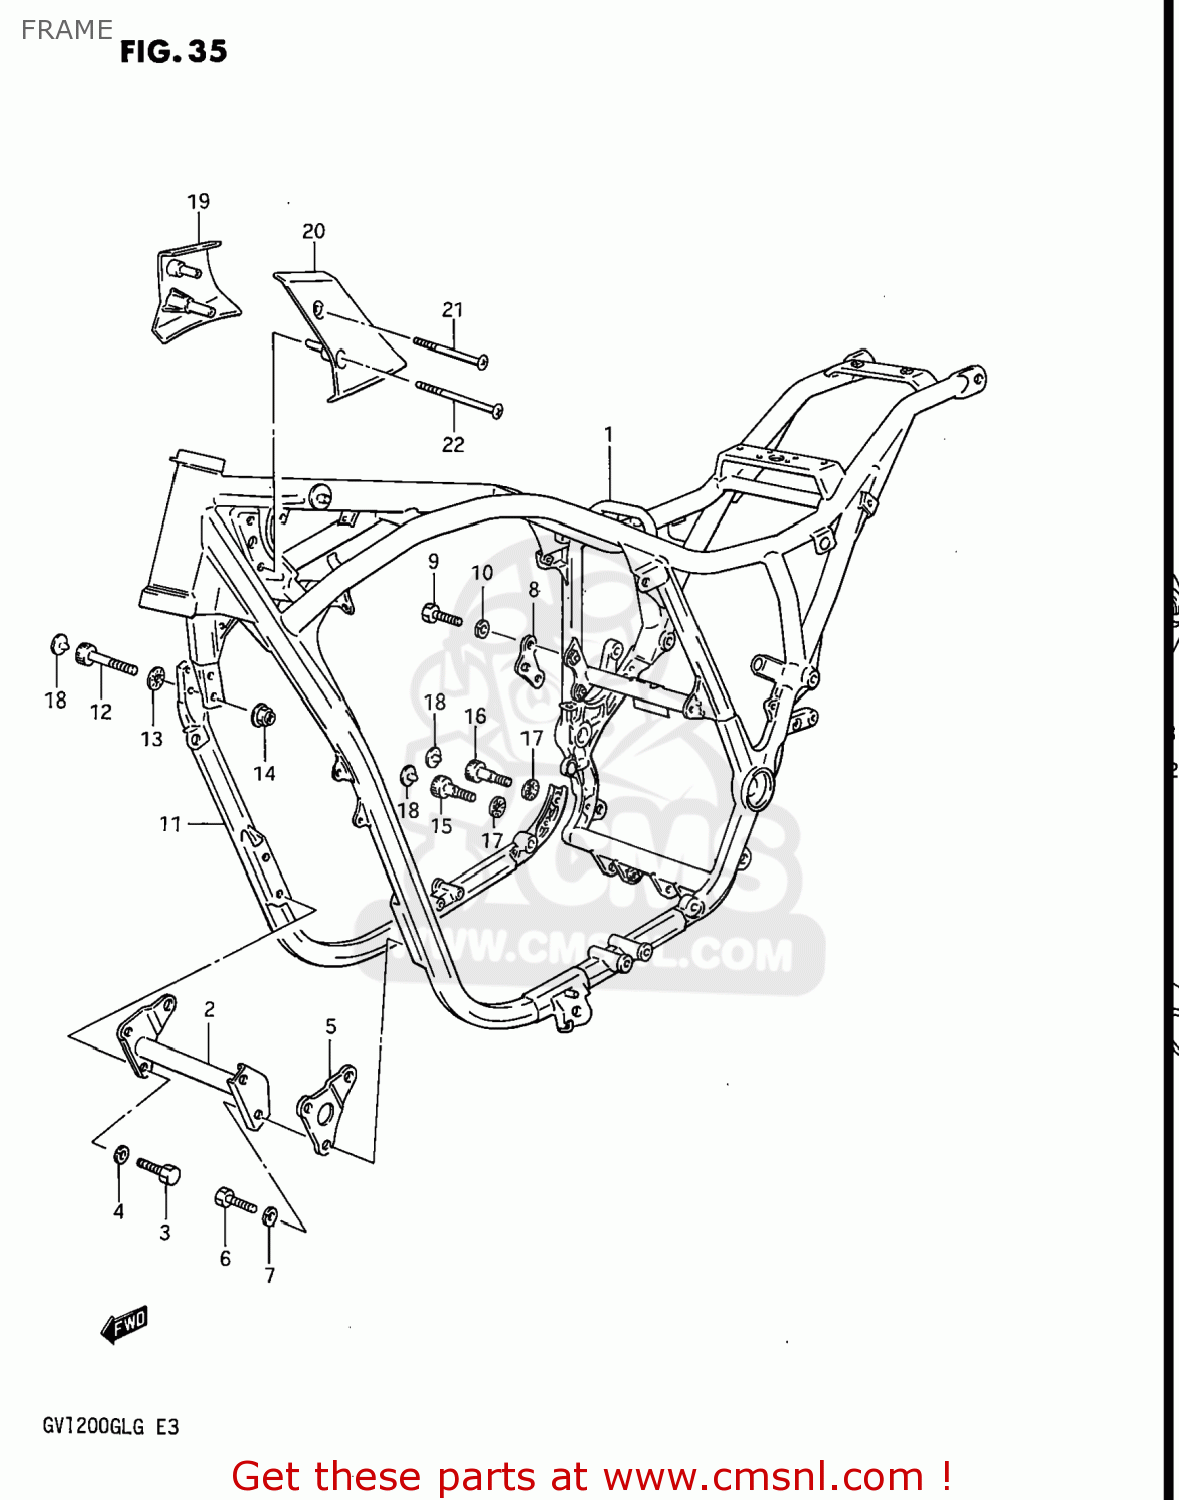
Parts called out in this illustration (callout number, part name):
1	FRAME
2	PLATE COMP,ENGINE MOUNTING
3	BOLT
4	WASHER,LOCK,8.
5	PLATE,ENGINE MOUNTING
6	BOLT
7	WASHER,LOCK,8.
8	PLATE,ENGINE MOUNTING
9	BOLT
10	WASHER,LOCK,8.
11	TUBE,FRAME DOWN,RIGHT
12	BOLT 10X38
13	WASHER
14	NUT 10MM
15	BOLT
16	BOLT
17	WASHER
18	CAP
19	COVER,FRAME HEAD,RIGHT
20	COVER,FRAME HEAD,LEFT
21	SCREW, LOWER
22	SCREW
